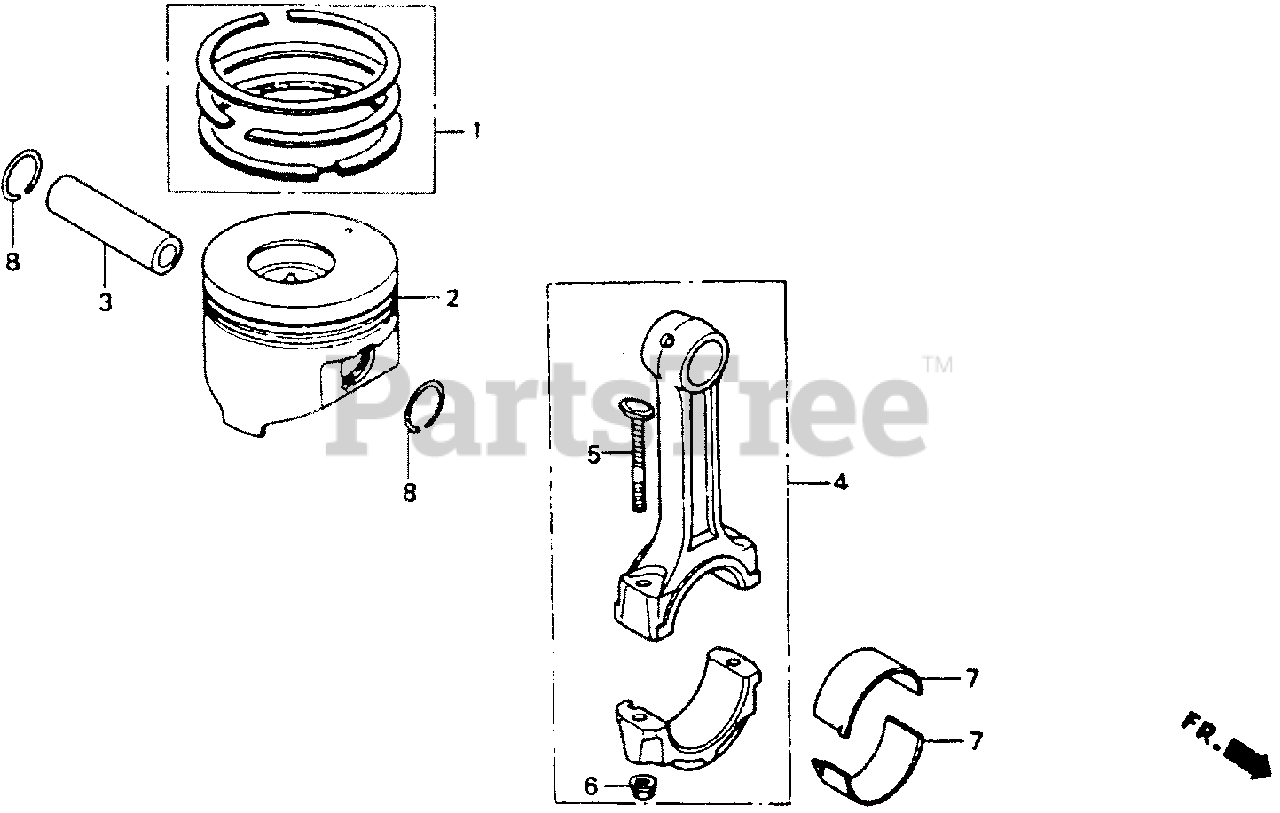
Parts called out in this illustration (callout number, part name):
1	RING SET, PISTON (STD)
1	RING SET, PISTON (OS 0.25)
1	RING SET, PISTON (OS 0.50)
1	RING SET, PISTON (0.75)
2	PISTON (STD)
2	PISTON (OS 0.25)
2	PISTON (OS 0.50)
2	PISTON (0.75)
3	PIN, PISTON
4	ROD ASSY., CONNECTING
5	BOLT, CONNECTING ROD (8X51)
6	NUT, CONNECTING ROD
7	BEARING A, CONNECTING ROD (BLUE)
7	BEARING B, CONNECTING ROD (BLACK)
7	BEARING C, CONNECTING ROD (BROWN)
7	BEARING D, CONNECTING ROD (GREEN)
7	BEARING E, CONNECTING ROD (YELLOW)
7	BEARING, CONNECTING ROD (F)(PINK)
7	BEARING G, CONNECTING ROD (RED)
7	BEARING A, CONNECTING ROD (US 0.25) (BLACK)
7	BEARING B, CONNECTING ROD (US 0.25) (BROWN)
7	BEARING C, CONNECTING ROD (US 0.25) (GREEN)
7	BEARING A, CONNECTING ROD (US 0.75) (BLACK)
7	BEARING B, CONNECTING ROD (US 0.75) (BROWN)
7	BEARING C, CONNECTING ROD (US 0.75) (GREEN)
8	CLIP, PISTON PIN
